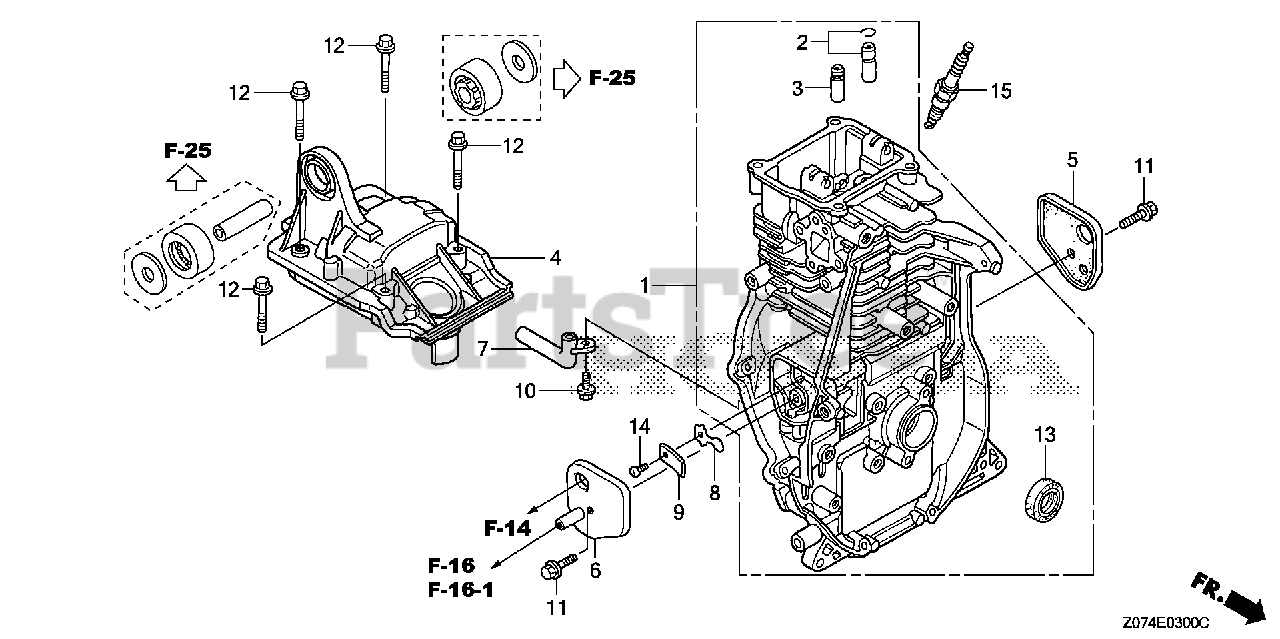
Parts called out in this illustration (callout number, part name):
1	CYLINDER ASSY.
2	GUIDE ASSY., EX. VALVE (OVER SIZE)
3	GUIDE, VALVE (OVER SIZE)
4	COVER, HEAD
5	COVER A, BREATHER
6	COVER B, BREATHER
7	PIPE, BREATHER
8	VALVE, OIL OUTLET
9	PLATE, STOPPER
10	BOLT (4X10)
11	BOLT, FLANGE (6X14)
12	BOLT, FLANGE (6X28) (CT200) Use up to Engine SN 1530314.
13	OIL SEAL (20X32X6)
14	SCREW, PAN (3X5)
15	SPARK PLUG (CR4HSB) (NGK)
15	SPARK PLUG (CR5HSB)
